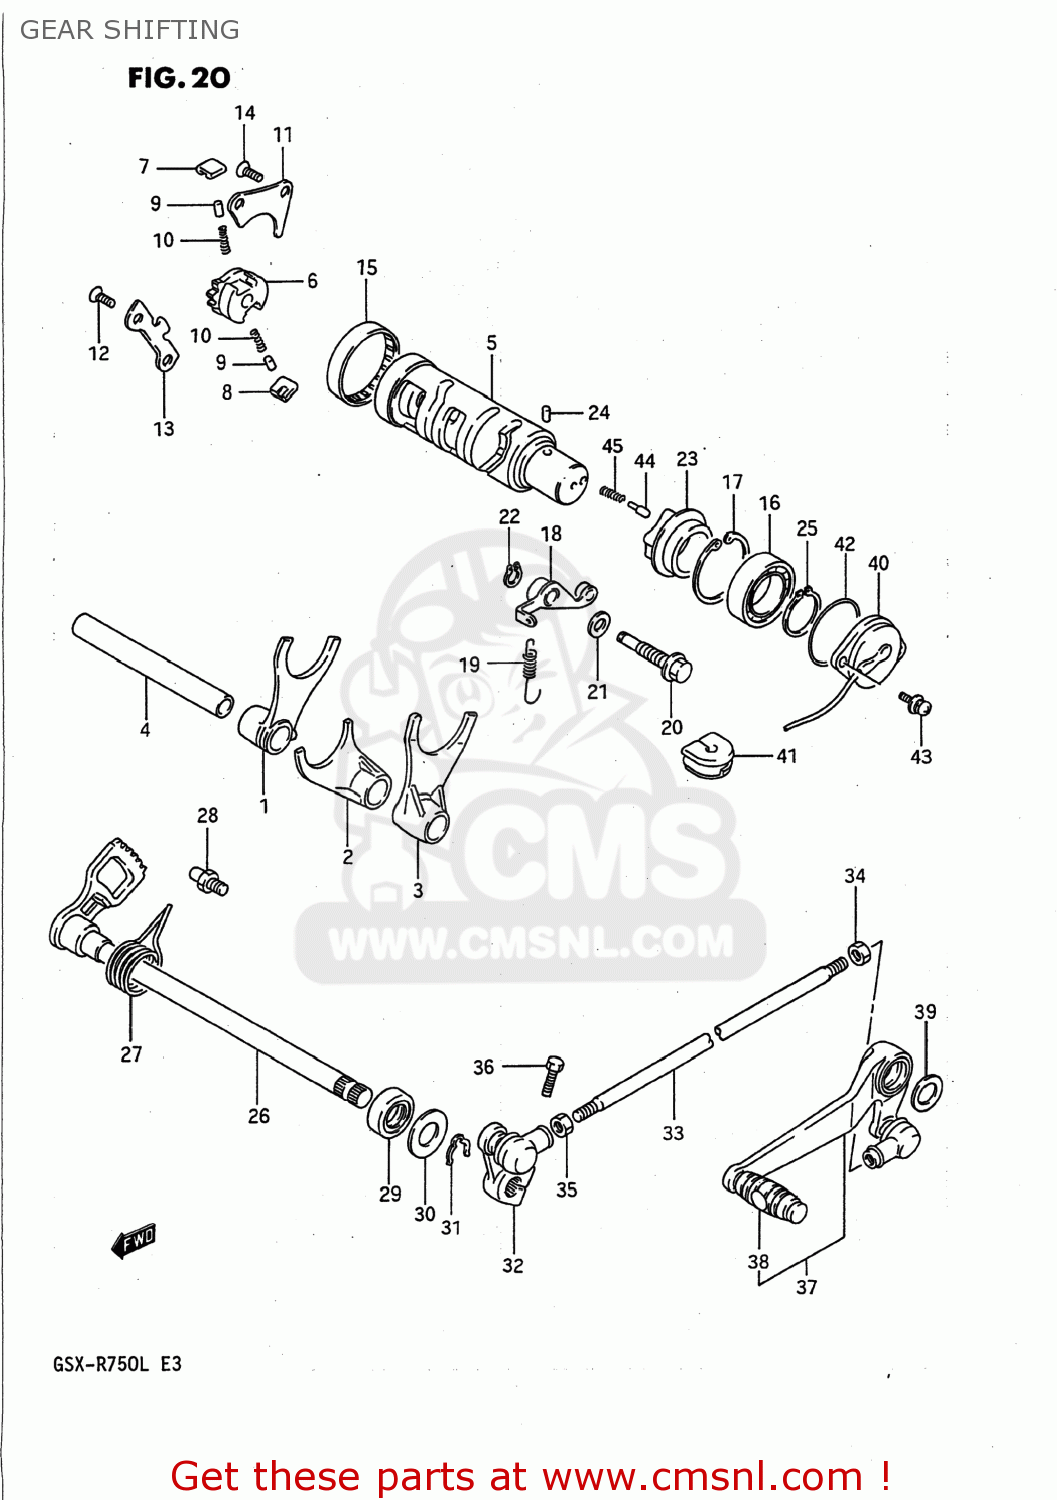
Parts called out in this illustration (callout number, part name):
1	FORK,GEAR SHIFT NO.1
2	FORK,GEAR SHIFT NO.2
3	FORK,GEAR SHIFT NO.3
4	SHAFT,GEAR SHIFT FORK(L:128)
5	CAM,GEAR SHIFT
6	GEAR,GEARSHIFT CAM DRIVE
7	PAWL,GEAR SHIFT NO.1
8	PAWL,GEAR SHIFT NO.2
9	PIN(5X8)
10	SPRING
11	LIFTER,GEAR SHIFT PAWL
12	SCREW
13	GUIDE,GEAR SHIFT CAM
14	SCREW
15	BEARING(43X49X12)
16	BALL BEARING
17	CIRCLIP,42MM
18	STOPPER,GEAR SHIFT CAM
19	SPRING
20	SHAFT,GEAR SHIFT CAM STOPPER
21	GASKET(10X14X3.6) (NAS)
22	CIRCLIP
23	PLATE,STOPPER
24	PIN 4X6
25	CIRCLIP,25MM
26	SHAFT,GEAR SHIFT
27	SPRING
28	STOPPER,GEAR SHIFT CAM
29	OIL SEAL
30	WASHER (12.5X27X1.6)
31	SPRING,RETAINER
32	ARM,GEAR SHIFT
33	ROD,GEAR SHIFT LINK
34	NUT
35	NUT 6MM
36	BOLT
37	LEVER ASSEMBLY,GEAR SHIFTING
38	RUBBER,GEAR SHIFT PEDAL
39	WASHER(18X24X1)
40	TERMINAL BASE ASSY,NEUTRAL
41	GROMMET,LEADWIRE
42	O RING(D:2.4,ID:36.5)
43	SCREW
44	PIN(5X15.5)
45	SPRING
